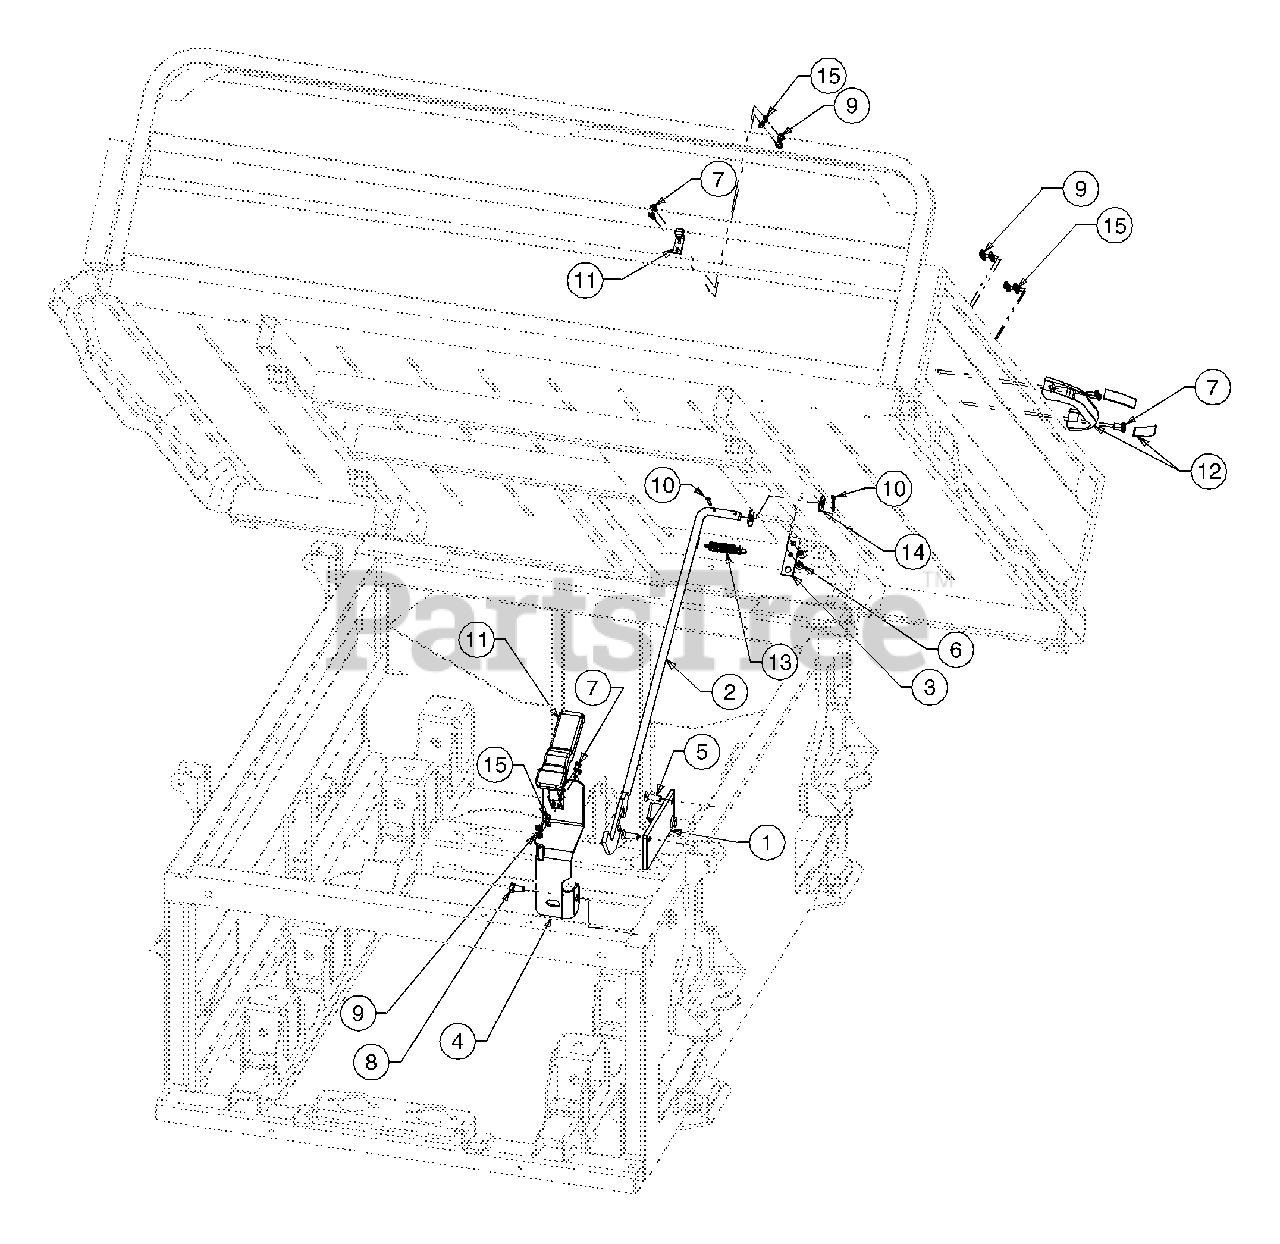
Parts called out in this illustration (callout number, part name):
1	Bracket Assembly, Prop Rod
2	Rod Assembly, Prop
3	Tab, Bed Lift
4	Bracket, Bed Latch Base
5	Screw, Countersunk Socket, 5/16-18 x 1
6	Screw, Self-tapping, 1/4-20, 0.50
7	Screw, Hex Sems, #10-32 x .62, Gr5
8	Hex Screw, 5/16-18 x .625, Gr5
9	Hex Nut, 10-32
10	Pin, Cotter, 0.125 OD
11	Latch Assembly, Bed
13	Spring, .497 OD x 1.935
14	Washer, Flat, .51 ID x 1.05
15	Washer, Lock, #10
